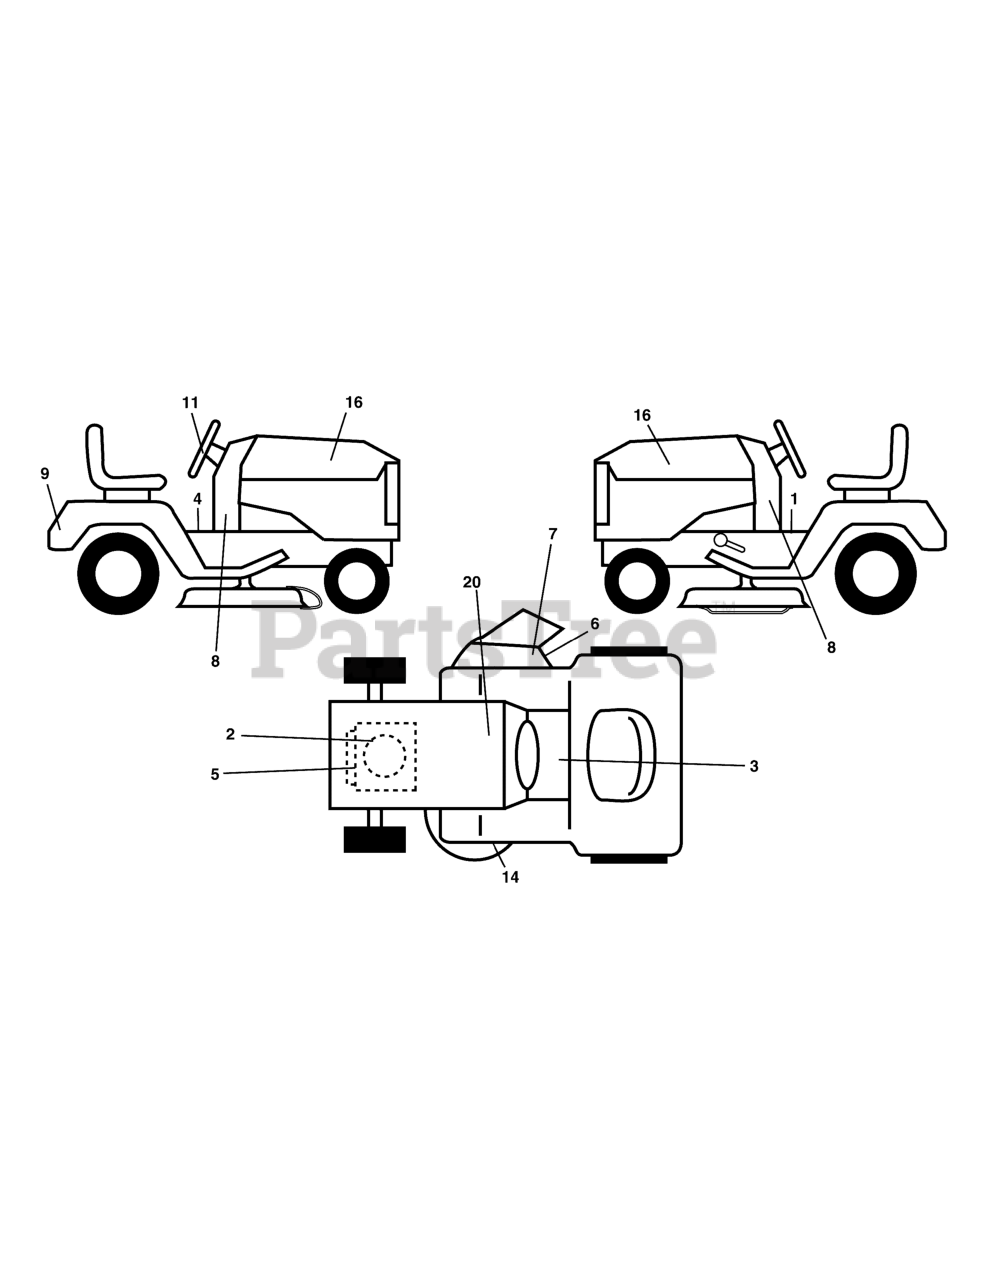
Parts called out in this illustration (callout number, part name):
1	Decal Brake/Clutch Symbol
2	Decal Engine H.P.
3	Decal Warning Symbols
4	Decal Saddle Brake Parking
5	Decal Warning Engine
6	Decal Warning, Keep Hand Away
7	Decal Deflect WRN. Cutfinger
8	Decal Dash Lower
9	Decal Fender Logo
11	Decal Ins Strg Whl
14	Decal V-Belt Schematic
16	Decal Hood LH/RH Set
20	Decal Bat Dan/Psn
